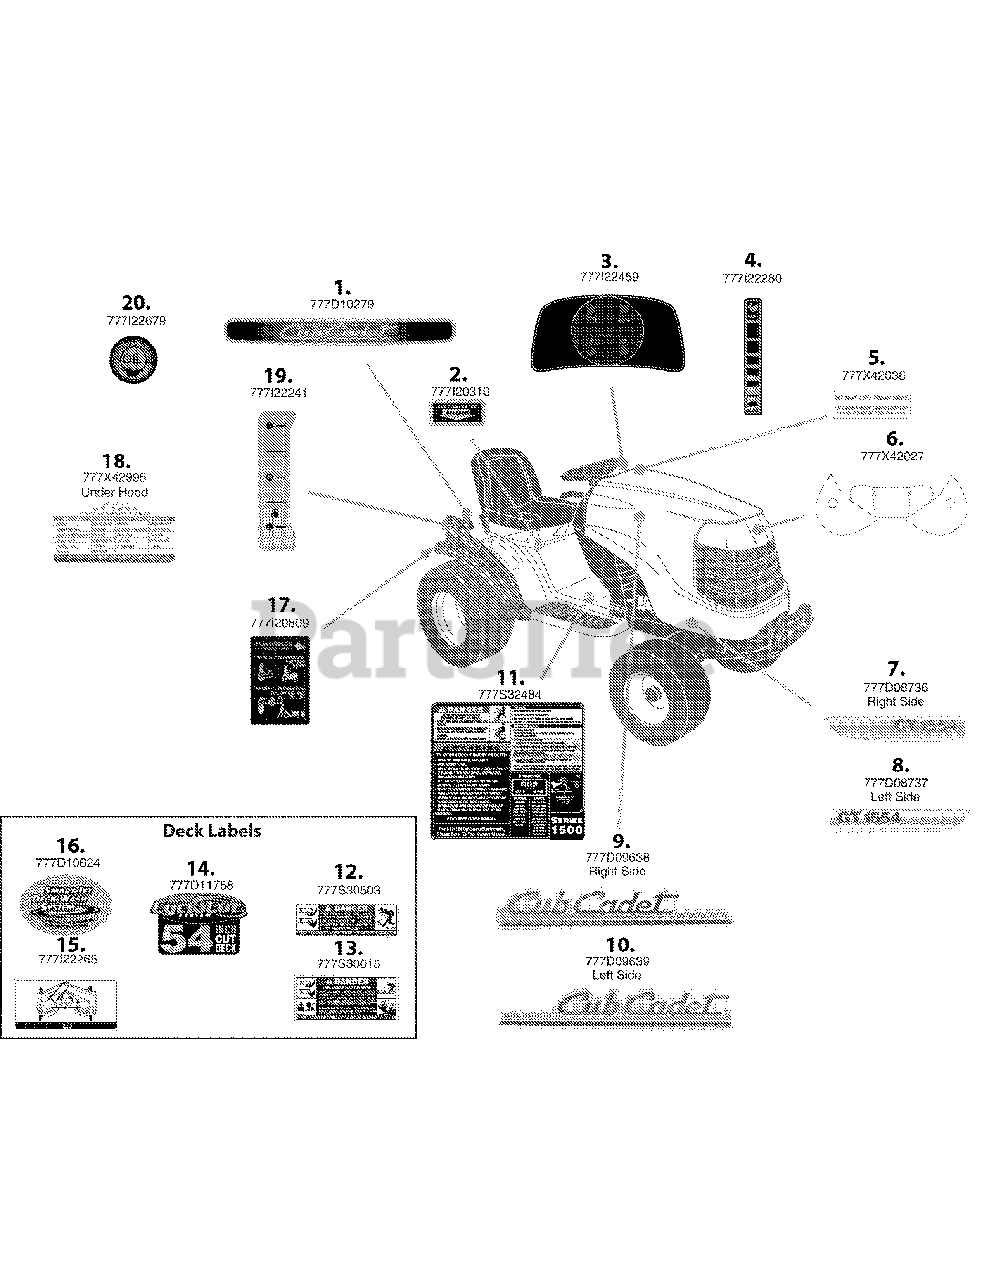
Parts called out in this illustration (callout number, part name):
1	LABEL-REAR FENDER
2	LABEL-SEAT ADJUSTE
3	LABEL-DASH PANEL
4	LABEL-THROTTLE
5	LABEL: CUB RIDER
6	LABEL-GRILLE REFLECTOR
7	LABEL-RH SIDE GT1554
8	LABEL-LH SIDE GT1554
9	LABEL-RGT SIDE HOOD
10	LABEL-LFT SIDE HOOD
11	LABEL-FRAME COVER
12	LABEL-DANGER CHUTE
13	LBL.RIDER DNGR.STRAIGT
14	LABEL-CYCLO CUT 54"
15	LABEL-BELT ROUTE
16	LABEL-RIDER:DECK WASH CUB
17	LABEL-HITCHPLATE
18	LABEL-PARTS LIST CUB GT1554
19	LABEL-FUEL LEVEL
20	LABEL-CHECK ENG OIL
